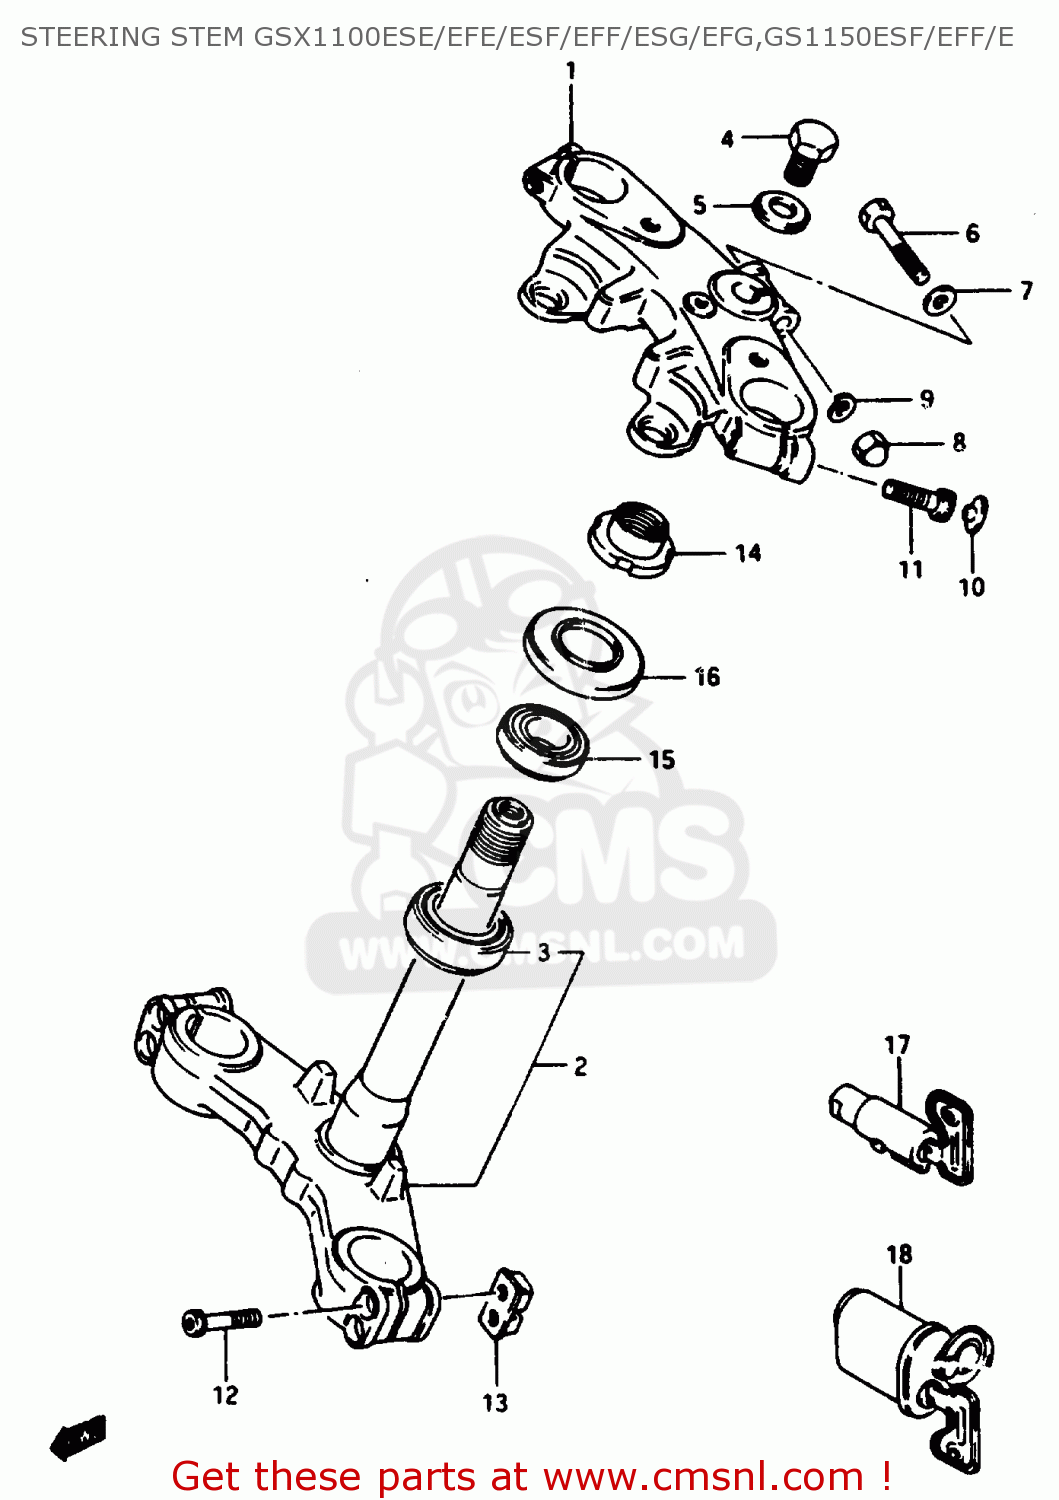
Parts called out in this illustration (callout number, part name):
1	HEAD,STEERING STEM
2	STEM,STEERING
3	BEARING
4	NUT,STEM HEAD
5	WASHER,STEERING STEM
6	BOLT
7	WASHER
8	NUT,M8X1.25X12
9	WASHER,LOCK,8.
10	CAP(OD:20)
11	BOLT,FORK INNER TUBE FITTING
12	BOLT 8X45
13	NUT,FR FORK INNER TUBE
14	NUT,STEERING STEM
15	TAPER,ROLLER BEARING
16	DUST SEAL,STEERING UPR
17	LOCK ASSEMBLY,STEERING (NEI
18	LOCK ASSY, STEERING (NEIMAN TYPE EXECUTE
